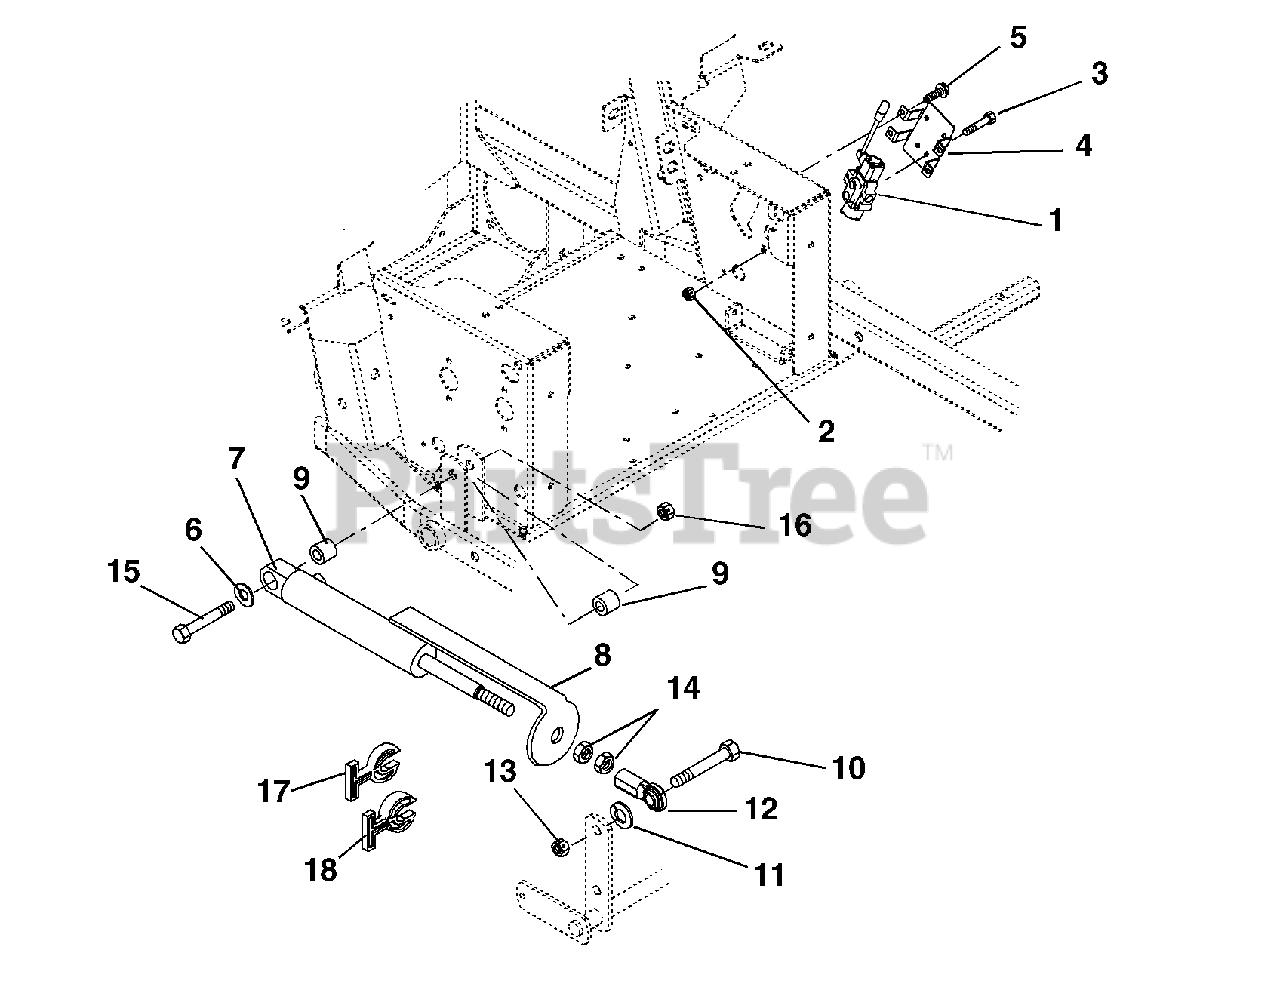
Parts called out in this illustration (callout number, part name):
1	Valve, Hydraulic
2	Nut-Locking-Nylon .31-18
3	Bolt-Hex .31-18 x 2.25 Grade 5
4	Bracket, Valve Mounting
5	Screw-Tapping .38-16 x .50 Hex Washer Head
6	Washer-Flat-Steel .515 x 1.625 x .25
7	Cylinder-Hydraulic Lift
8	Strap-Height of Cut Indicator
9	Bushing .516 x 1.000 x 1.050
10	Bolt-Hex .62-11 x 2.25 Grade 8
11	Washer-Lock .62 x .156
12	Rod End-Right Hand-Female 5/8
13	Nut-Locking-Center .62-11
14	Nut-Jam .625-18
15	Post, Cylinder Stop
16	Nut-Locking-Center .50-13
17	Stop, Cylinder .34 Thick
18	Stop, Cylinder .68 Thick
